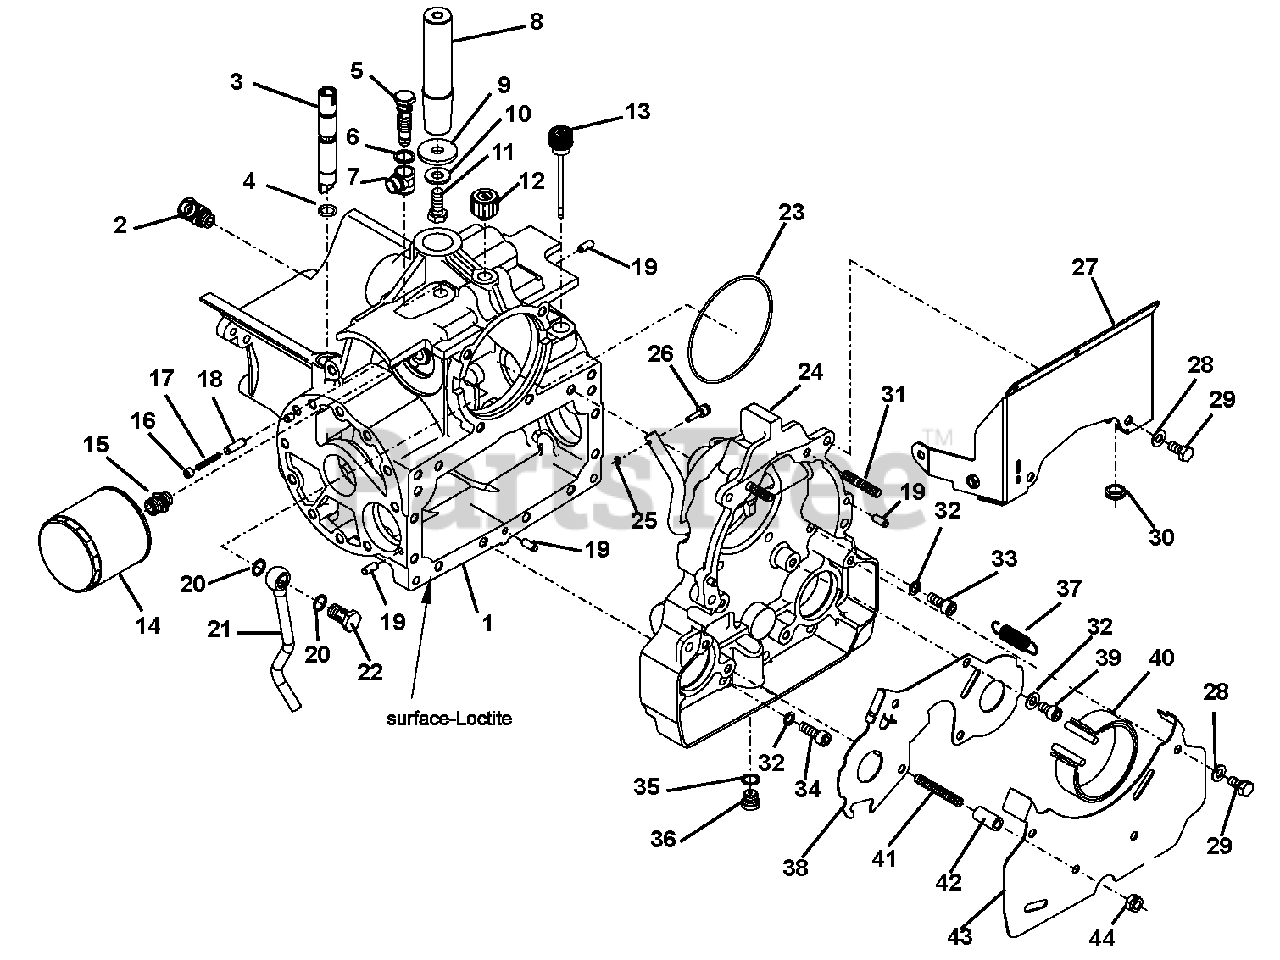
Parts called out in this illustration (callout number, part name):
1	Gearbox, Case
2	Swivelling Screw Fitting, XSWV
3	Stay Shift
4	Warning Triangle, 15.00 x 3.00
5	Banjo Bolt, M16 x 1.5
6	Ring, Joint 18 x 34
10	Turnbuckle, 13.0 x 293.0
11	Bolt, Hex, D933 M12 x 30
12	Screw, Replenishing M16 x 1.5
13	Screw, Lock
14	Filter Suction
15	Connector, 3/4 M16 x 1,5
16	Threaded Pin, M10 x 8
17	Spring, Pressure
18	Pin, Lock
19	Pin, Straight BN 855 8-H8 x 20
20	Ring, Joint, D7603A 16 x 20 CU
21	Pipe, Suction
22	Banjo Bolt, D7643 NW10
23	Warning Triangle, D3770
25	Washer, Retaining 4mm
27	Cover Plate
29	Bolt, Hex M10 x 20
30	Bushing Socket, 14 x 18 x 2
31	D835, M10FO x 35
32	Washer, FORM Z 10.2/16.1 x 1.6
33	Screw, D912 M10 x 25
34	Screw, D912 M10 x 30
35	Ring, Joint, D7603A 16 x 20 CU
36	Drain, Plug, D908 Metric 16 x 1.5MG
37	Spring, Tension
38	Support Bearing
39	Screw, D912 M10 X 16
40	Brake Band
41	Threaded Pin, D913 M10 x 70
42	Support Tube
44	Nut, Lock M10
